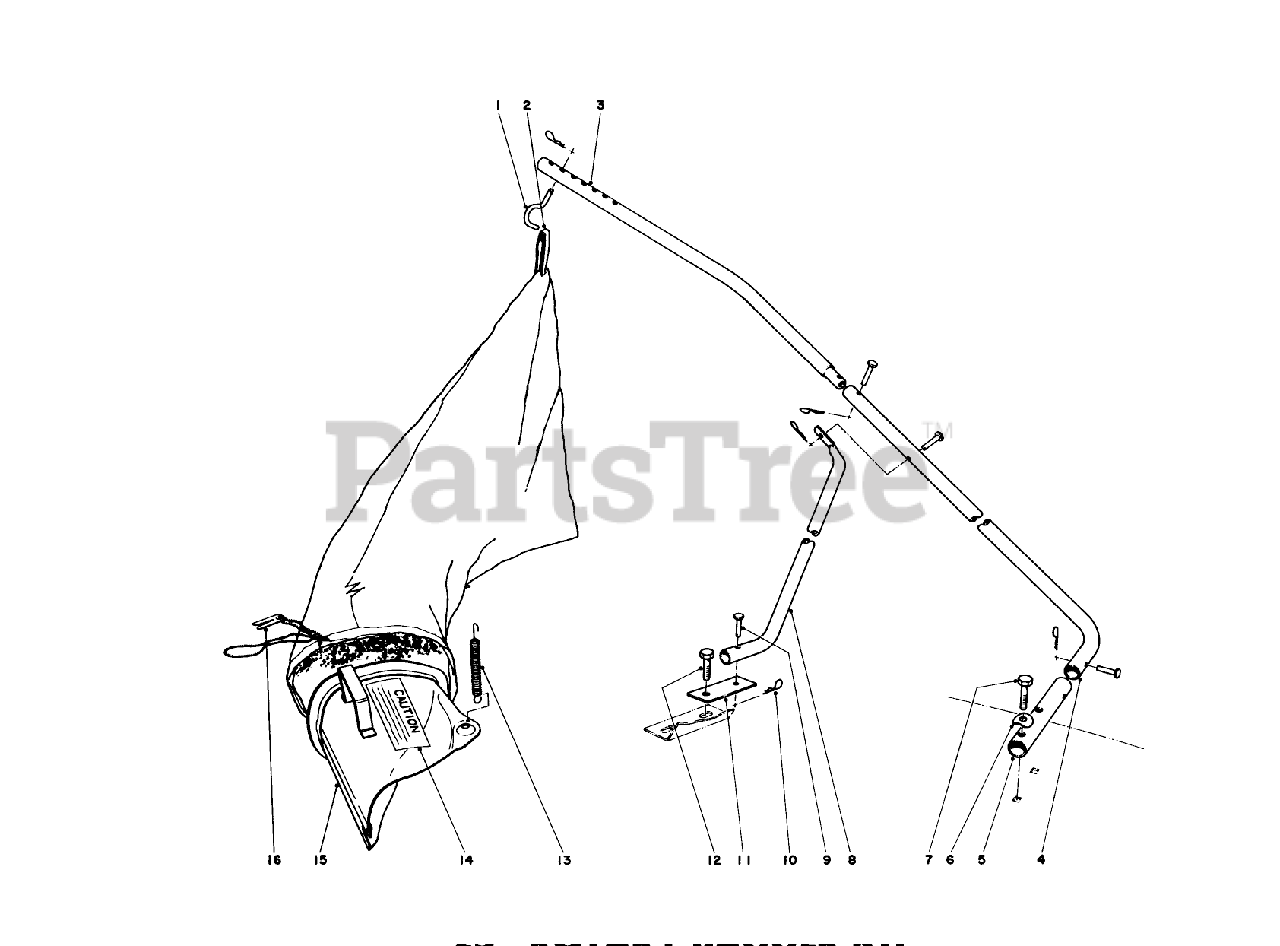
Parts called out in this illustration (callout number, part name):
2	Giant Bag
3	Long Bag Arm
5	Socket-Bag Arm
6	Curved Washer
7	SCREW-HH
8	Brace
10	PIN-COTTER
11	Brace Support
12	SCREW-HH
13	Spring
14	Decal
15	Bag Chute (Incl. Ref. Nos. 13 & 14)
16	BAG CORD FASTENER
